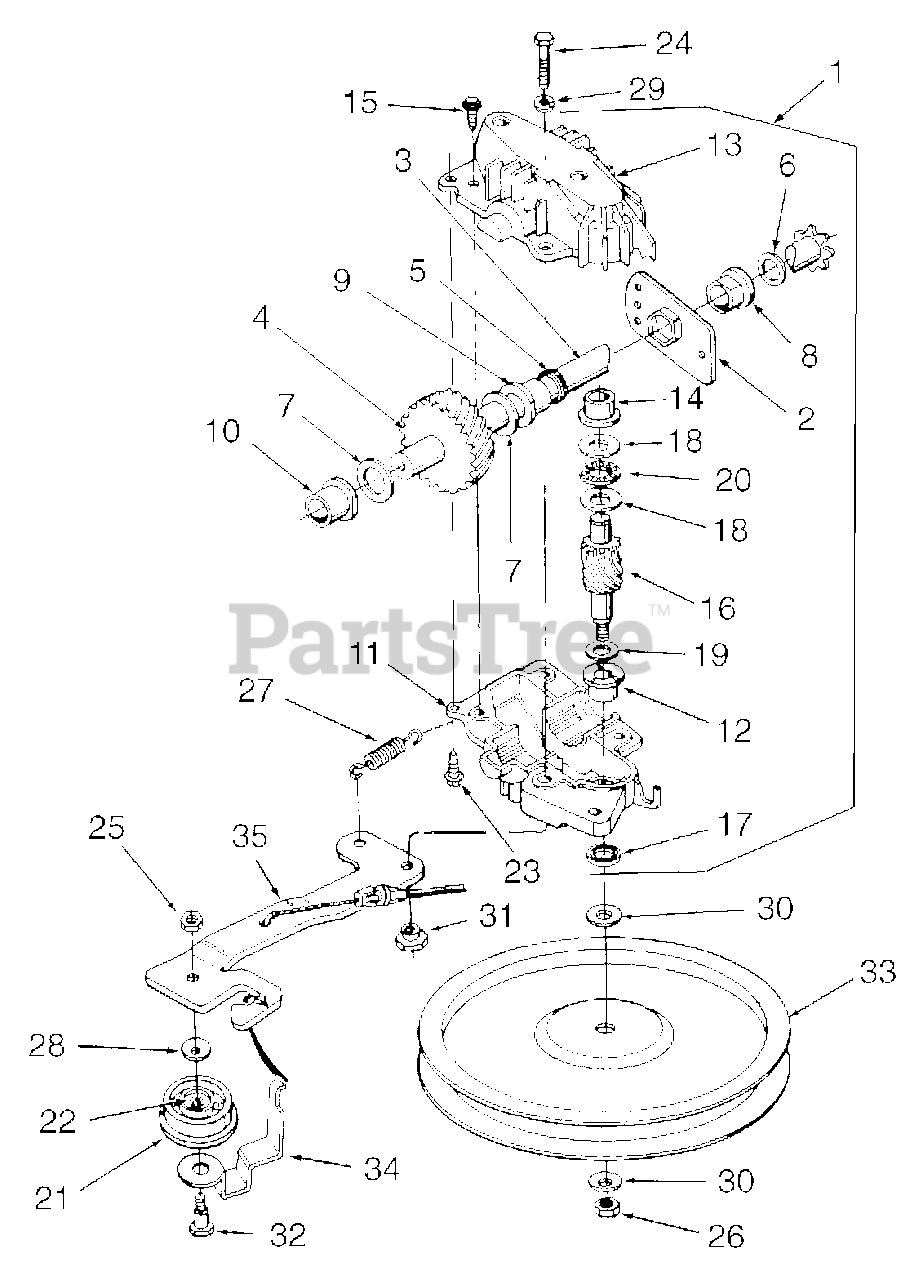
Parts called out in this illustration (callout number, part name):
1	Transmission Assembly, Complete
3	Shaft, Output w/6T Sprocket
4	Gear, Helical 34T
5	Seal, Oil, .625 x .812
6	Washer, Flat, .64 x 1.24 x .06 HD
7	Washer, Flat, 5/8 x 1.0
8	Bearing, Hex Flange, .631 ID
9	Bearing, Flange, .629 ID
10	Bearing, Flange, .566 ID
11	Housing, Lower
12	Bearing, Flange, .503 ID
13	Housing, Upper
14	Bearing, Flange, .378 ID
15	Screw, Hex Tapp, #10-16 x .75
16	Shaft, Pinion 10T
17	Seal, Oil, .50 x .687
18	Washer, Thrust, .382 x .684
19	Washer, Flat, .504 x .70 x .030
20	Bearing, Thrust, .375 x .812
21	Pulley Ass'y, Idler w/Bearing,
22	Bearing, Needle, .375 x .375
23	Screw, Hex Tapp, #10-16 x .75
24	Screw, Hex w/Patch, 1/4-20 x 1.25
25	Nut, Hex, 1/4-28
26	Nut, Hex Jam, 5/16-24 L.H. Thd
27	Spring, Extension, 1.12 Lg
28	Washer, Bell, .265 x .75 x .06
29	Washer, Lock, 1/4
30	Washer, Bell, .325 x .930 x .045
31	Shoulder Spacer, .375 x .165
32	Shoulder Bolt, 1/4-28 x .375
33	Pulley, Flat, 5.06 Dia
34	Belt Keeper
35	Bracket, Idler
